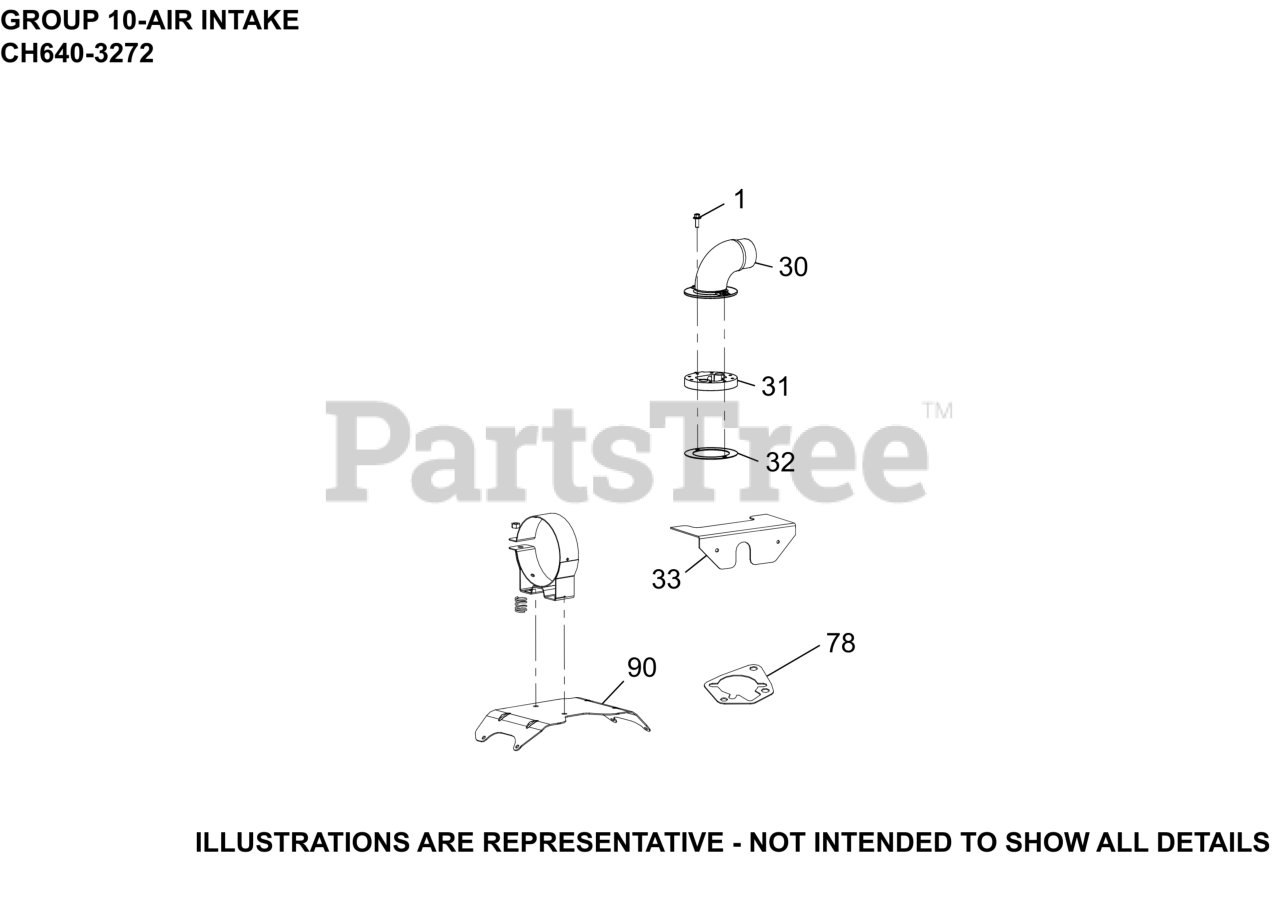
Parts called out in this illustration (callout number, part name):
1	SCREW, FLG M6X1.0X16
30	ADAPTER, REMOTE AIR CLEANER
31	ADAPTER ASSY
32	GASKET, ADAPTER
33	SHIELD, DEBRIS
78	GASKET, AIR CLEANER BASE
90	BRACKET, AIR CLEANER
